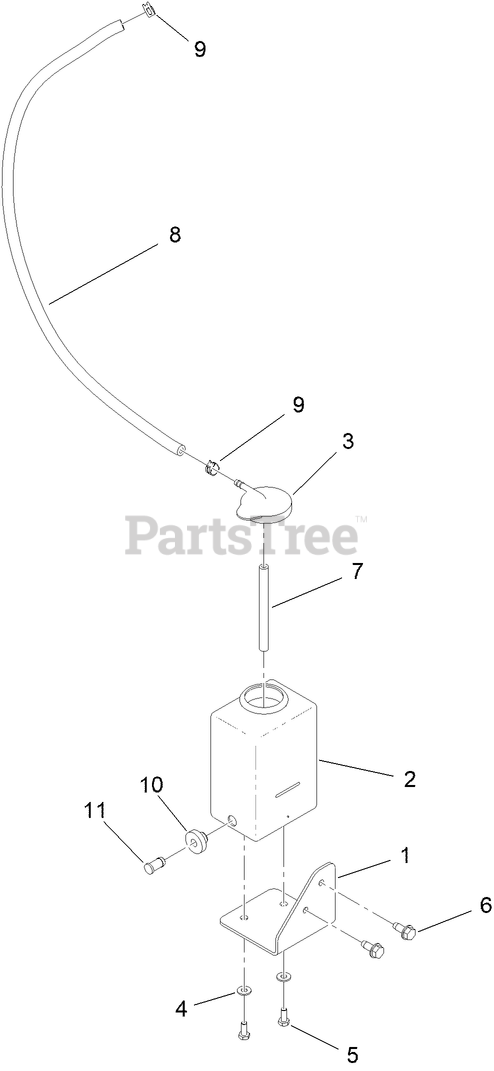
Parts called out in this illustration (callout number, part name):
1	MOUNT-TANK,OVERFLOW
2	TANK-OVERFLOW
3	CAP-TANK, OVERFLOW
4	WASHER-FLAT
5	SCREW-HH LOCK
6	SCREW-HWHTF
7	HOSE-FUEL
8	HOSE-FUEL
9	CLAMP-HOSE
10	BUSHING
11	PLUG-GROMMET
